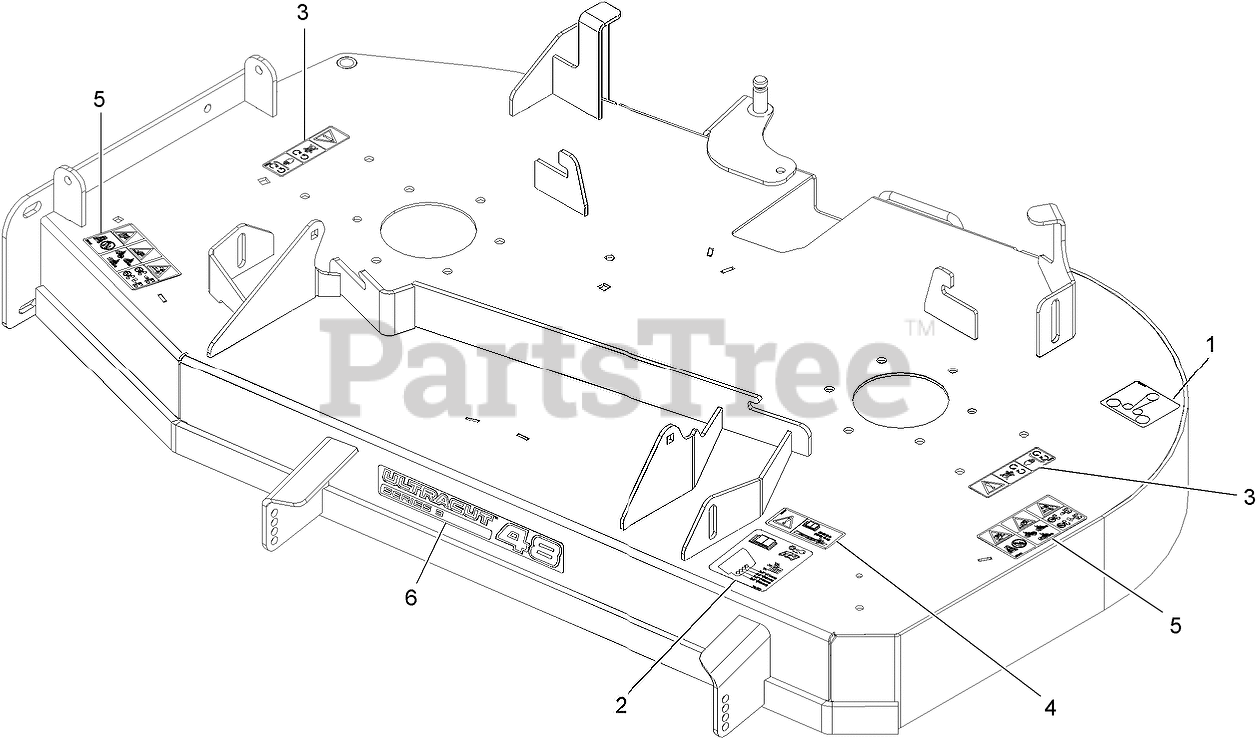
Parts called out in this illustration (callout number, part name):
1	DECAL-ROUTING, BELT
2	DECAL-ROLLER, ANTI-SCALP
3	DECAL-COVER, MISSING
4	DECAL-TORQUE, BOLT
5	DECAL-DANGER THROWN OBJECTS
6	DECAL-ULTRACUT 48 SERIES 3
